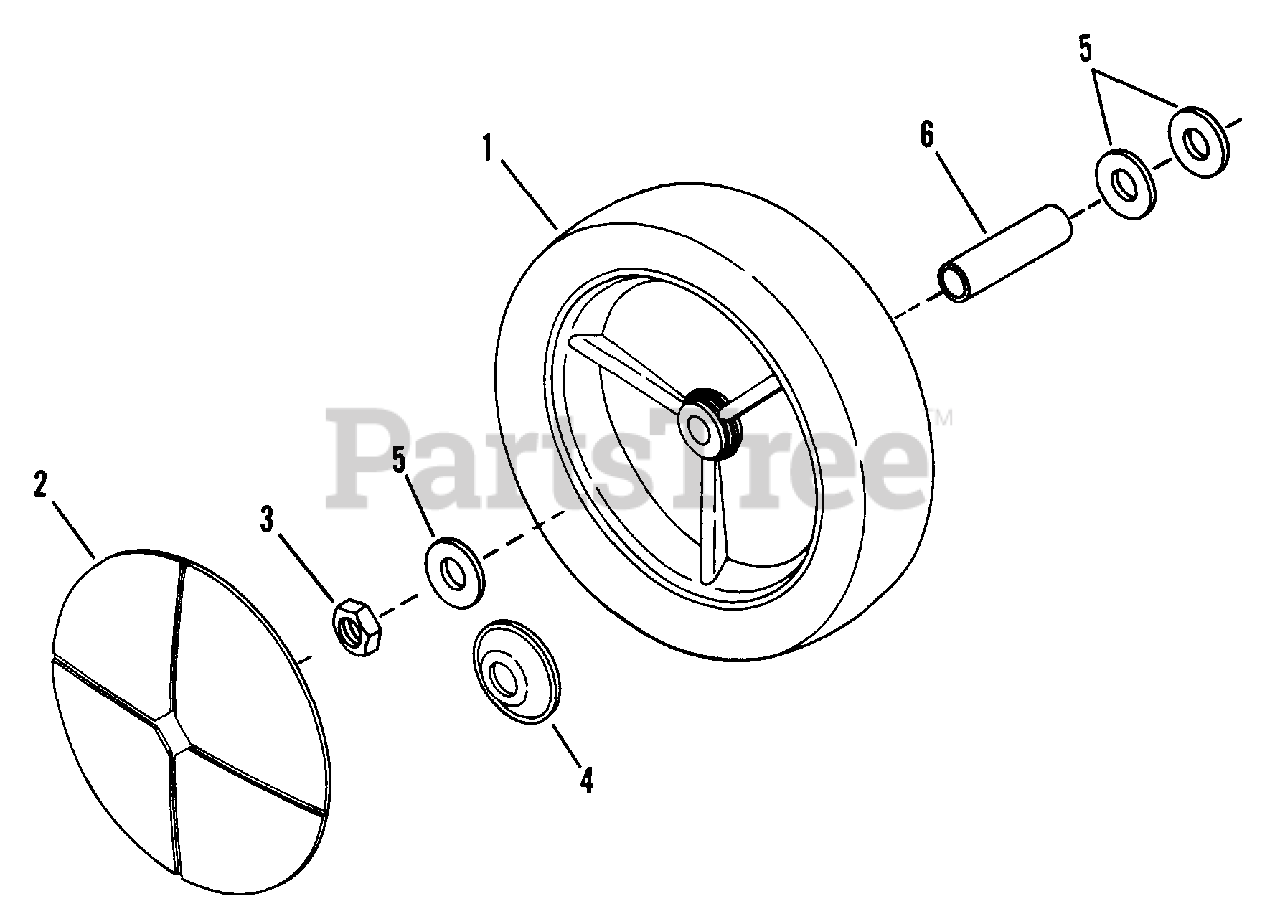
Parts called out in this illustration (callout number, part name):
1	WHEEL, 7 x 1.75 Plastic Rim
2	COVER, Wheel
3	NUT, 7/16-20 Hex Center Lock
4	CAP, Deep-Dish Hub
5	WASHER, 7/16 Flat
6	BUSHING, Axle
